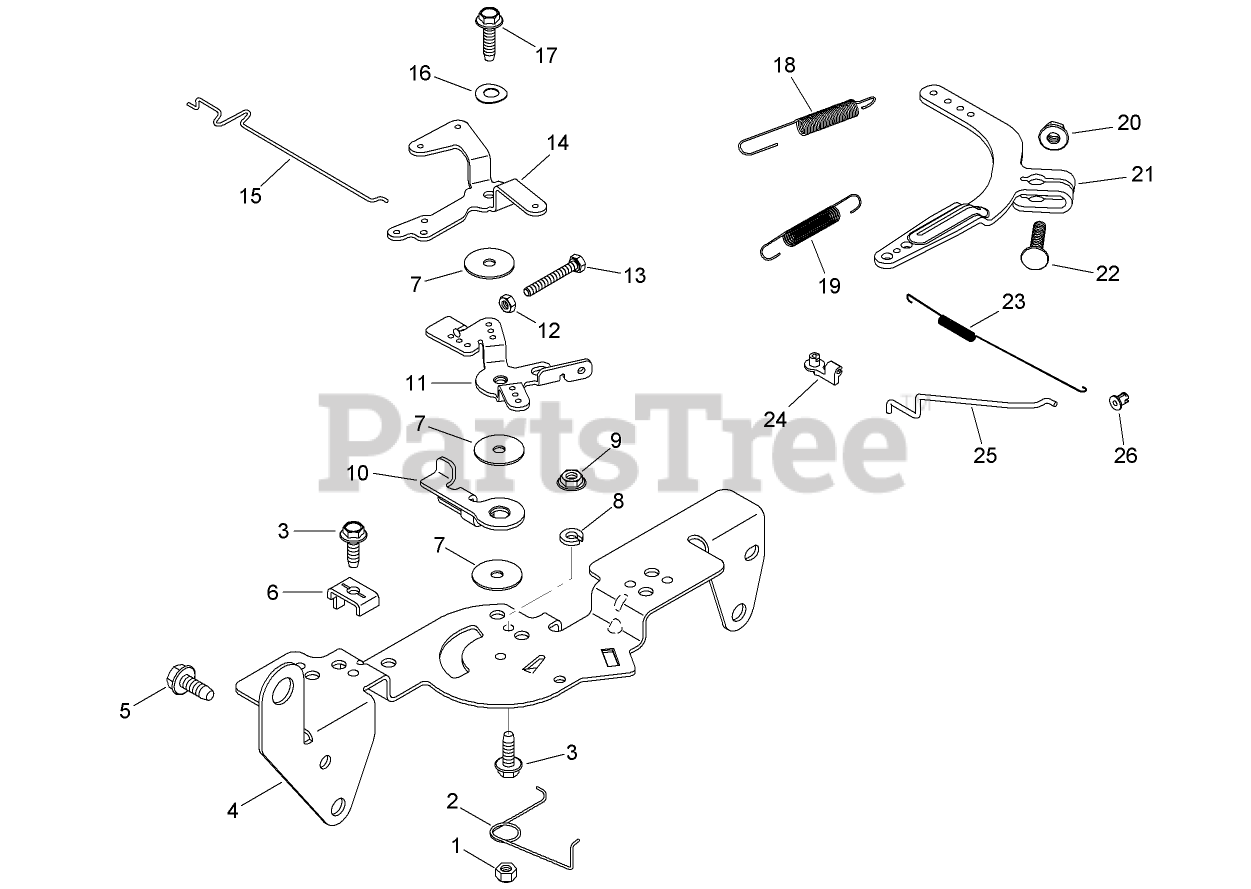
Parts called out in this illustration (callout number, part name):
1	NUT-LOCK (M5X.8)
2	SPRING-RETURN, CHOKE
3	SCREW-FLANGE, THREAD FORMING (M5X0.8X16)
4	Bracket-Control
5	SCREW-FLANGE, THREAD FORMING (M6X1.0X16)
6	CLAMP-CABLE
7	WASHER-FLAT (5.5MM)
8	Washer-Lock (.25)
9	Nut-HF (M5x0.8)
10	Lever-Actuator, Throttle
11	Lever-Control, Throttle
12	NUT (M4X0.7)
13	Screw (M4x0.7x30)
14	LEVER-CHOKE
15	Linkage-Choke
16	WASHER-SPRING (1/4)
17	SCREW-FLANGE, THREAD FORMING (M5X.8X20)
18	Spring-Limiter, Throttle
19	Spring-Governor
20	NUT-FLANGE (M6X1.0)
21	Lever-Governor
22	BOLT-SQ NECK, RD HD (M6X1.0X25)
23	SPRING-LINKAGE
24	BUSHING-RETAINING, LINKAGE
25	Linkage-Throttle
26	BUSHING-LINKAGE, THROTTLE
